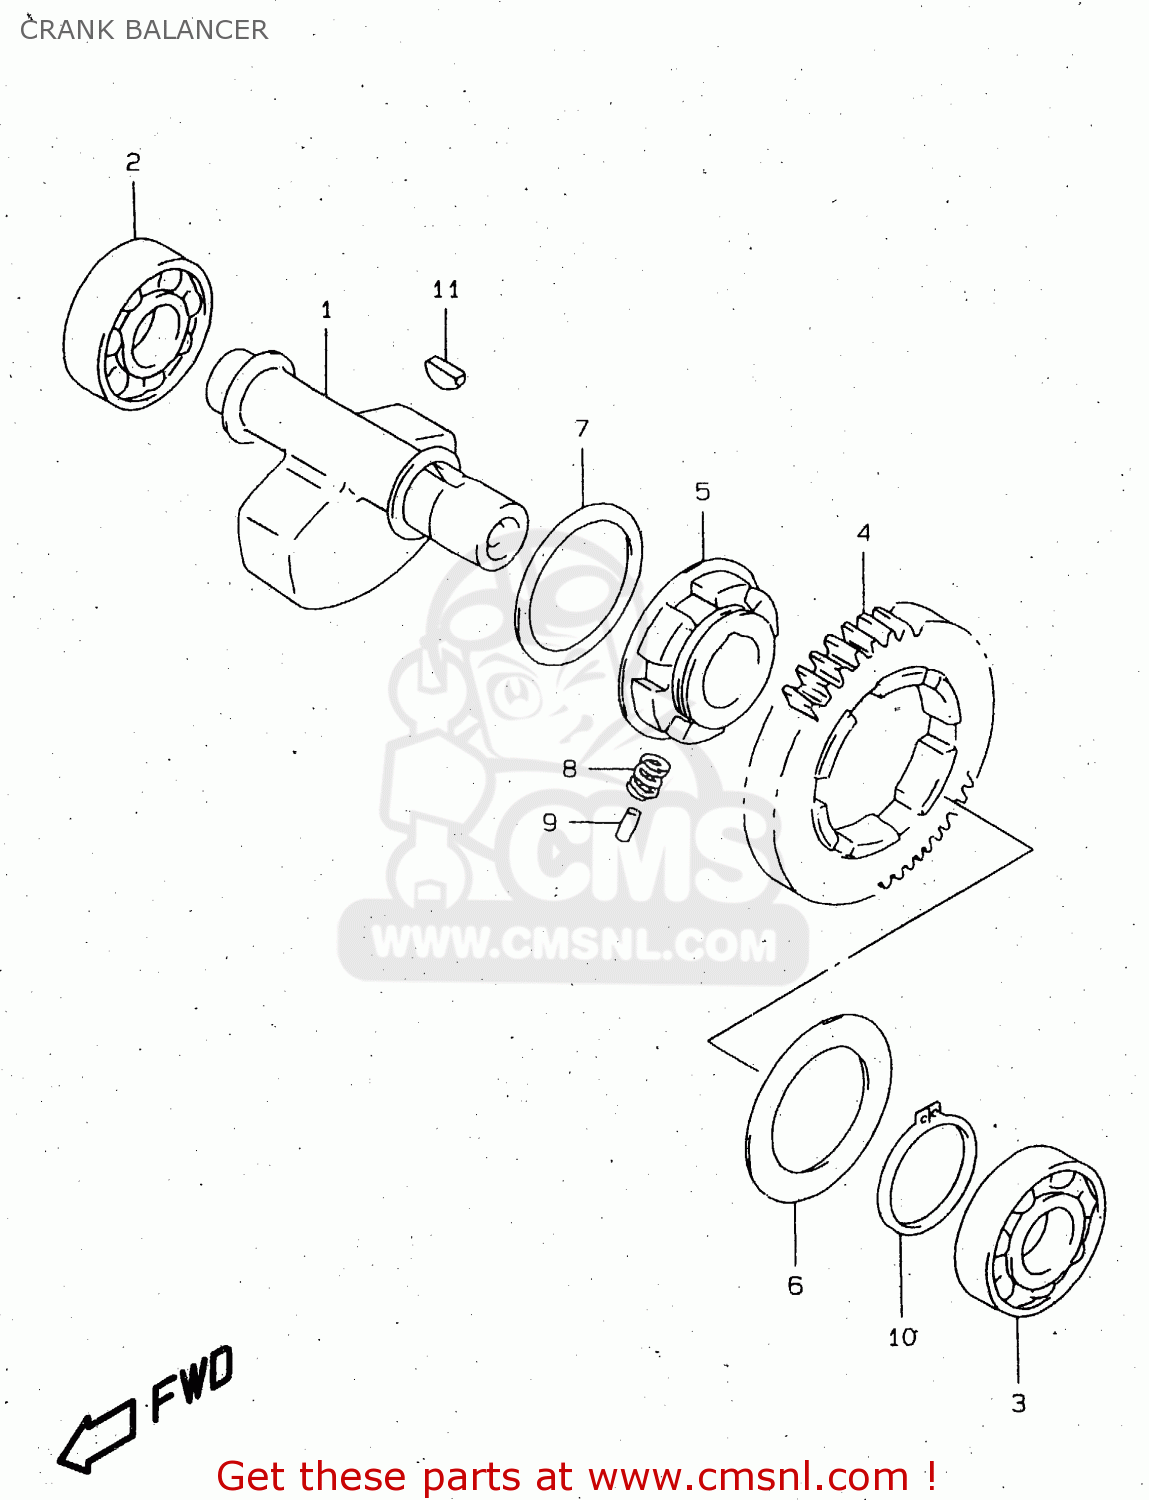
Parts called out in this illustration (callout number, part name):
1	BALANCER,CRANK
2	BEARING(22X56X16)
3	BEARING(20X47X14)
4	GEAR,CRANK BAL DRIVEN(NT:43)
5	RACE,CRK BAL DRIVEN GR INNER
6	WASHER
7	WASHER
8	SPRING
9	PIN(4.5X9.5)
10	CIRCLIP
11	KEY
